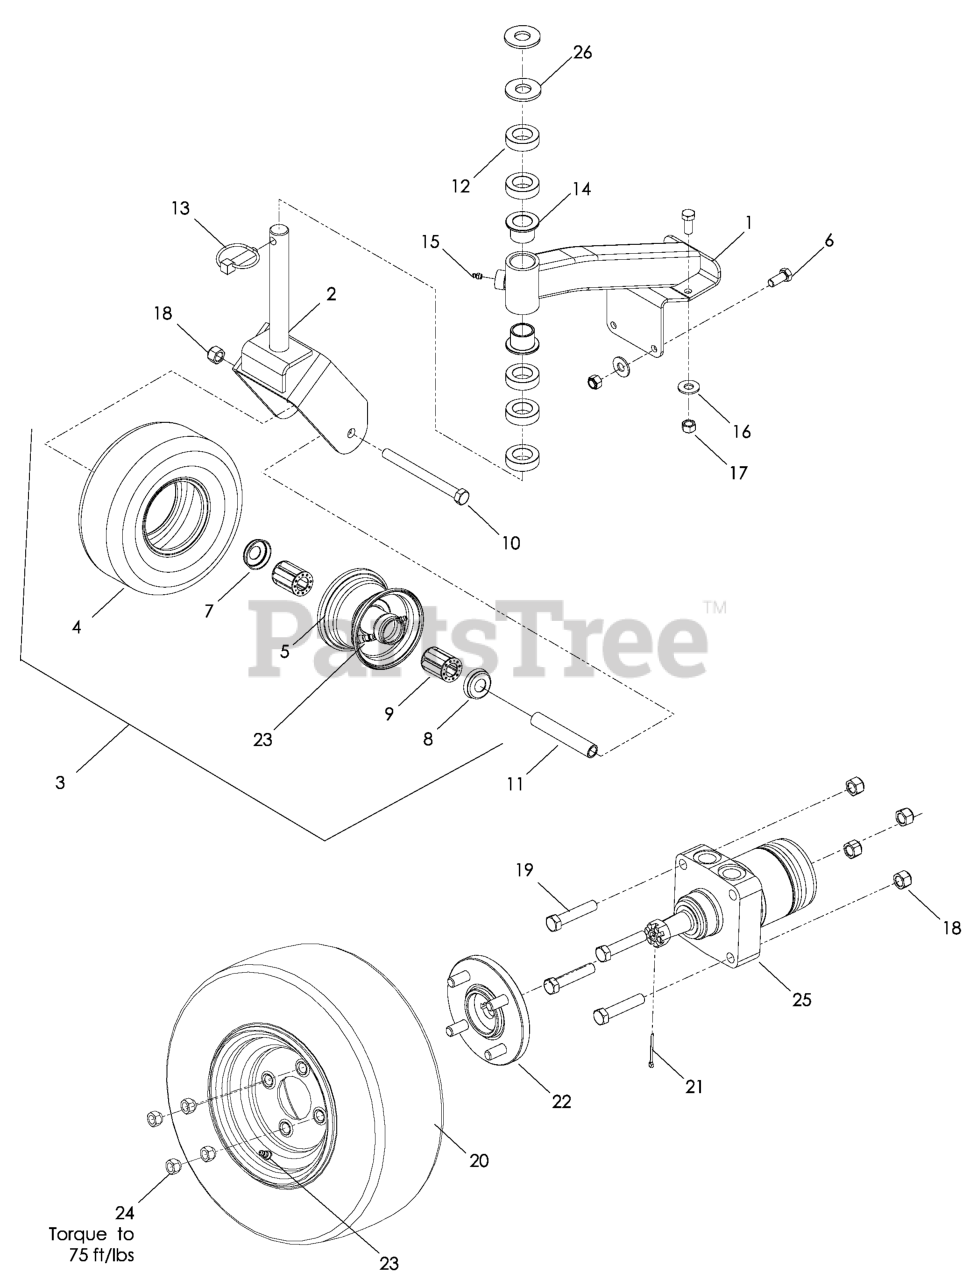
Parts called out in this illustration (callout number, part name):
1	CASTER SUPPORT ORANGE
2	CASTER WELDMENT PAINTED
3	TIRE/WHEEL.CASTER.9X3.5-4.SMOO
4	TIRE 9 X 3.5 - 4
6	HCS 3/8-16 X 7/8 GR 5 ZD
7	ENDCAP
8	ENDCAP, NOTCHED
9	ROLLER BEARING
10	HCS 1/2C X 5 1/2
13	LYNCH PIN 7/16
14	BSHG 1.003X1.252X1.75 LG OIL
15	ZERK
16	WASHER 3/8 FLAT
17	NUT 3/8-16 NYLOC
18	NUT 1/2-13 HEX NYLOC ZD
19	HEX SCREW 1/2-13 X 2.5" GR 5
20	WHEEL ASSY, 16 X 7.5-8
21	COTTER PIN
22	HUB, WHEEL
23	VALVE STEM TR-412
24	LUG NUT 1/2F
25	WHEEL MOTOR
26	SPACER, .25 HEIGHT ADJ
